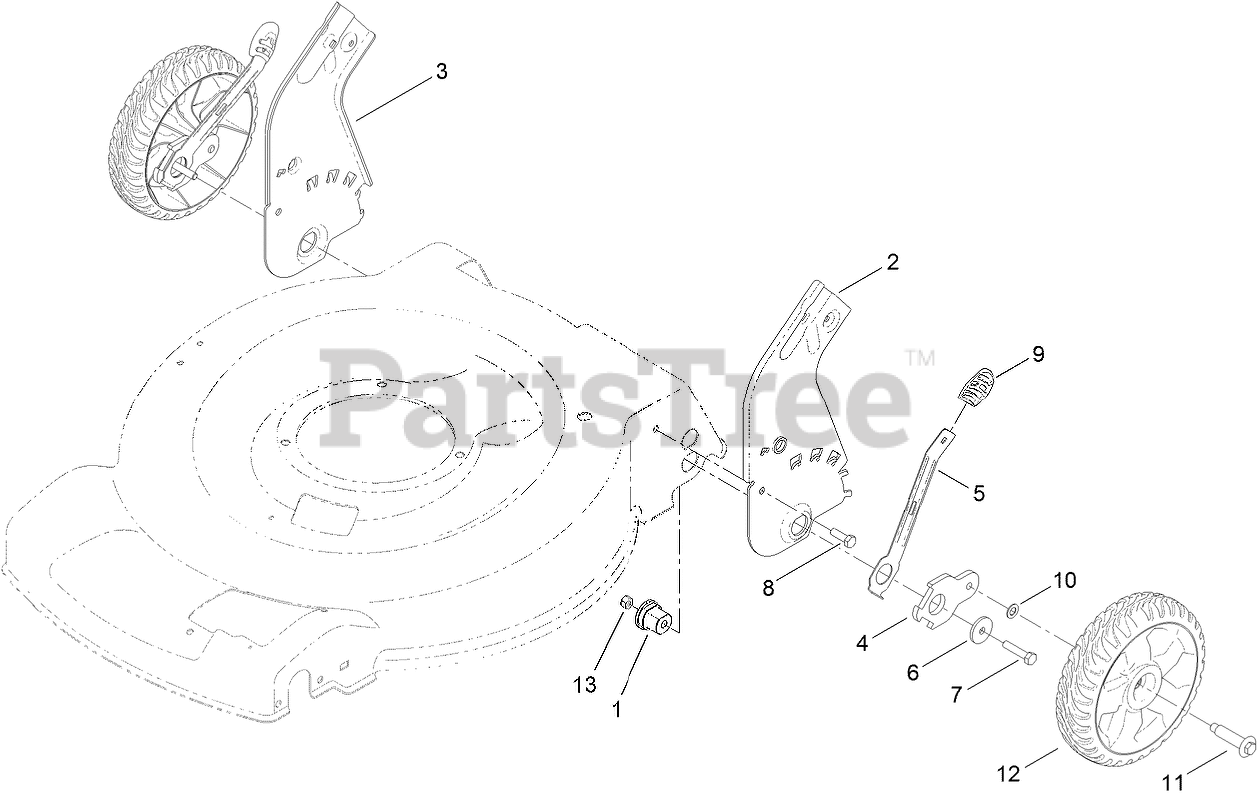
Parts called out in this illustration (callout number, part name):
1	BUSHING-MOUNT, HOC
2	PLATE-HOC, REAR (LH)
3	PLATE-HOC, REAR (RH)
4	ARM-PIVOT, REAR
5	ARM-SPRING, REAR
6	Washer-Flat
7	SCREW-HH
8	SCREW-HH
9	Knob-Lever, HOC
10	WASHER
11	BOLT-SHOULDER
12	8 INCH WHEEL ASM
13	NUT-LOCK, NI
